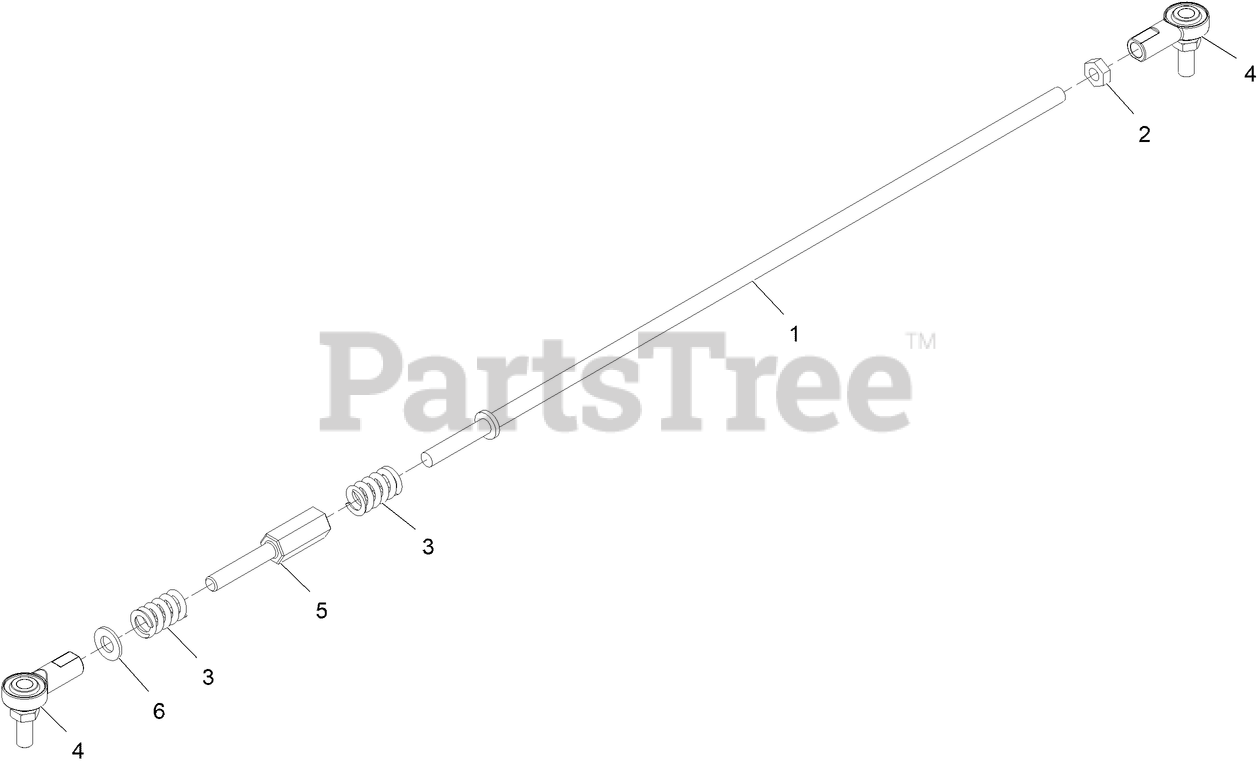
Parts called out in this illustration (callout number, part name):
1	ROD MOTION CONTROL LONG
2	NUT-JAM
3	SPRING-COMPRESSION
4	BALLJOINT
5	ROD-ADJUST
6	WASHER-PLAIN
